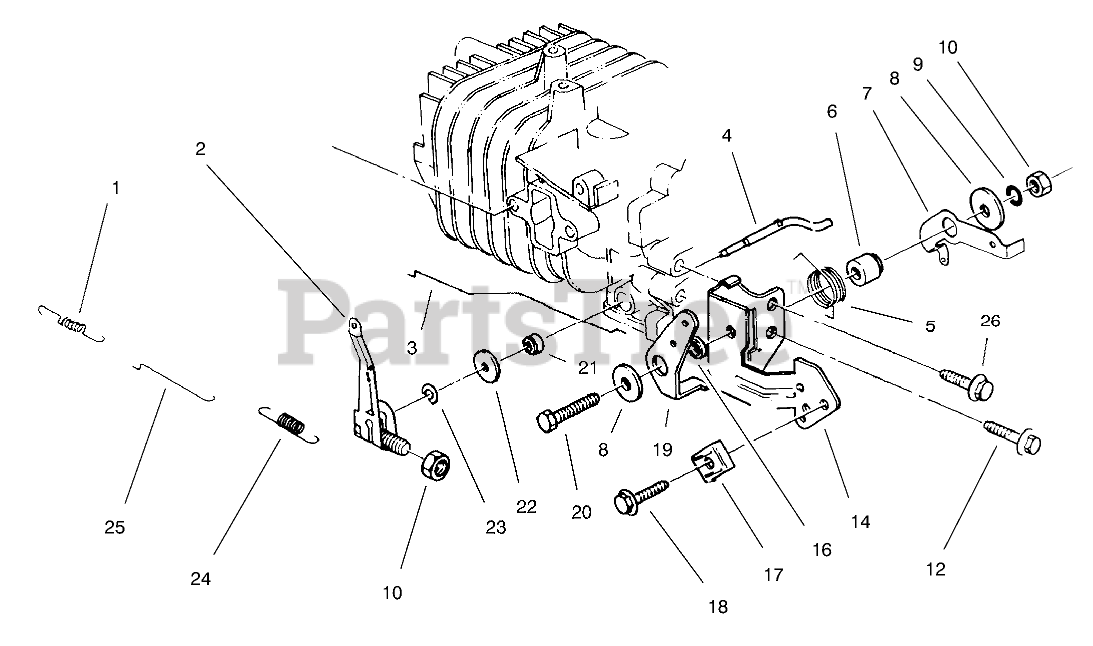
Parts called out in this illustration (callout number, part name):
1	SPRING
2	ARM-GOVERNOR
3	ROD-CHOKE
4	Shaft-Govemor
5	SPRING-CHOKE LEVER
6	Gov Lever Spacer
7	LEVER-SPRING, GOVERNOR
8	WASHER
9	LOCKWASHER
14	BRACKET-THROTTLE, CONTROL
16	SPACER-CHOKE LEVER
17	CLAMP
19	LEVER-CONTROL, CHOKE
21	SEAL-OIL
22	WASHER
23	E-RING
24	SPRING-GOVERNOR
25	ROD-CARBURETOR
